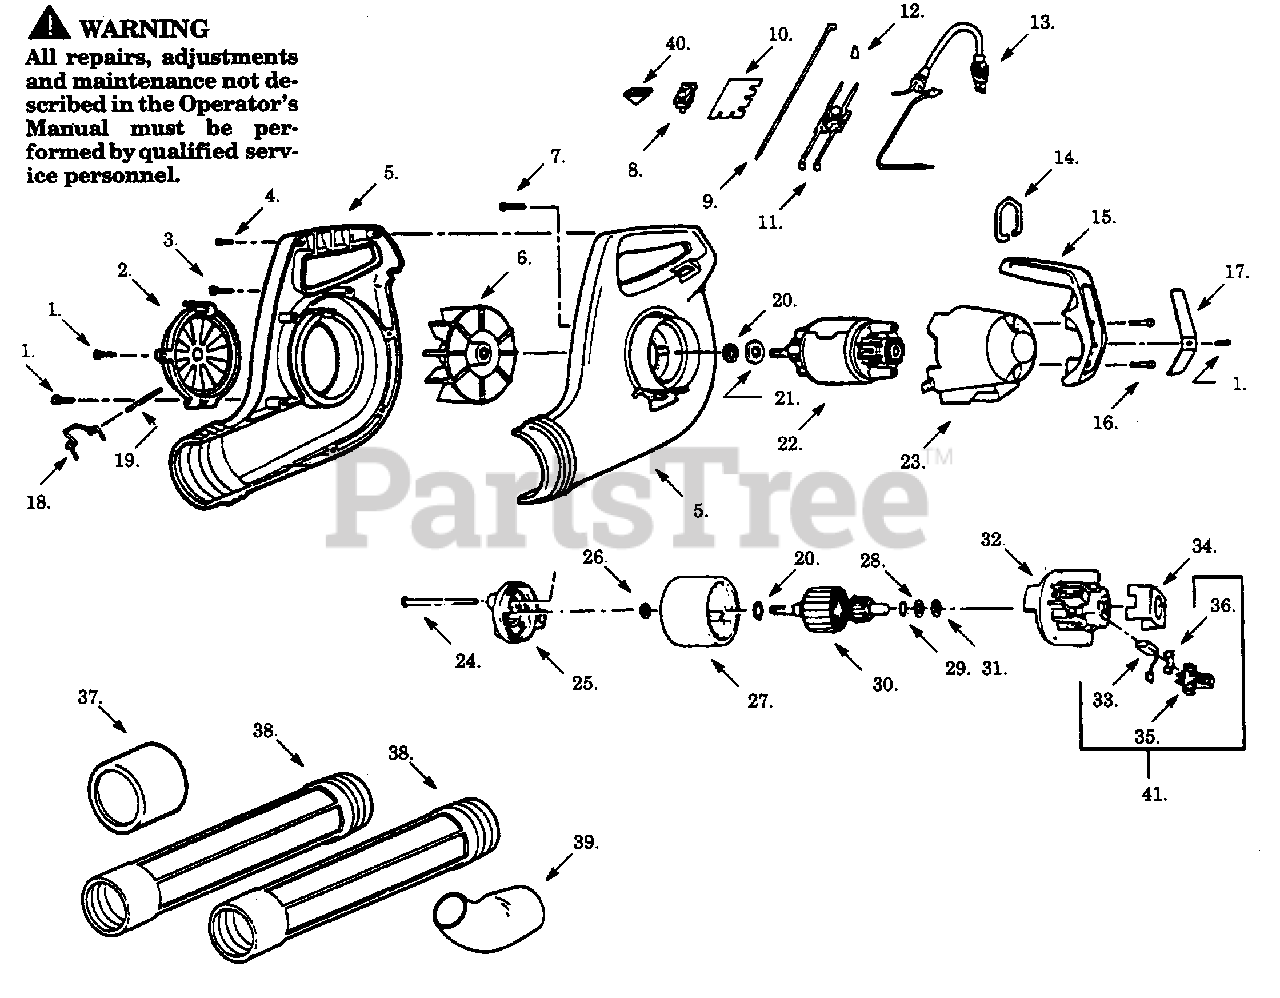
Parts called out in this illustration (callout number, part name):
2	Inlet Cover
5	Housing Set
6	Impeller Ass'y
9	Lead Wire Ass'y
10	Mounting Board
11	PC Board
12	Connector
13	Power Cord
14	Hanger Bracket
19	Hinge Pin
20	Retaining Ring
22	Motor Ass'y
23	Motor Housing
25	End Bell Ass'y
26	Shim Washer
27	Field Ass'y
28	Shim Washer
29	Retaining Ring
30	Armature Ass'y
32	End Bell
34	Insulator
35	Brush Holder
38	Outlet Tube
40	Switch Cover
41	Brush Kit (Incl. 33,35,36)
